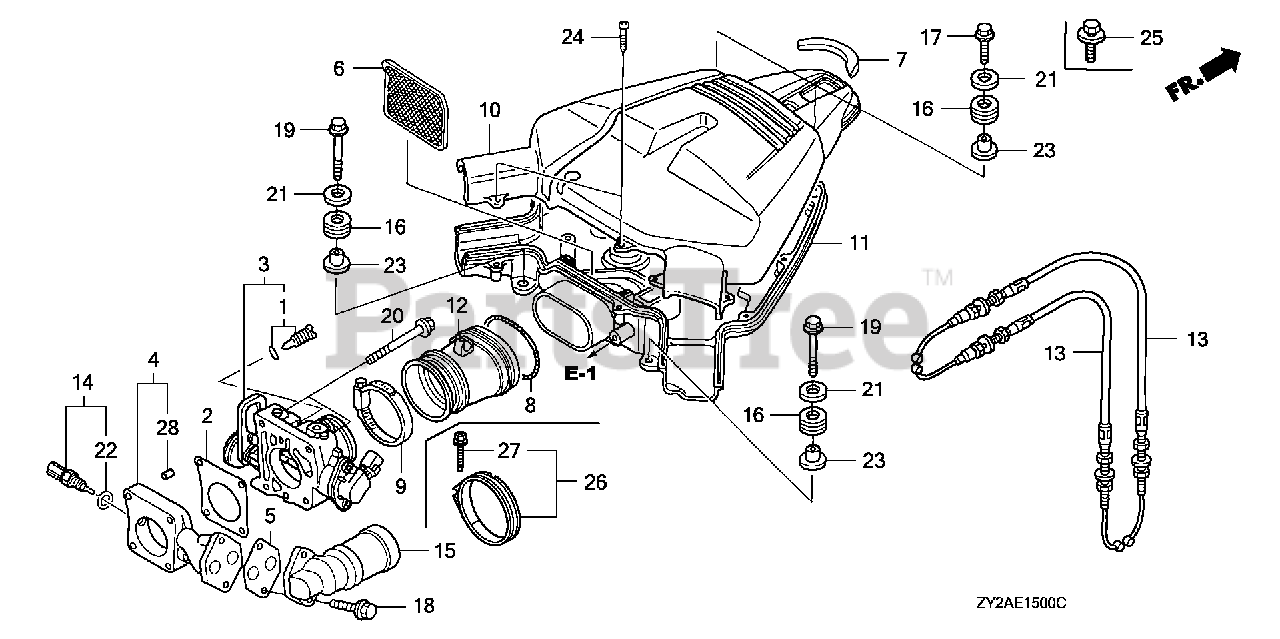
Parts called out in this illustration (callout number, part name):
2	GASKET, THROTTLE BODY
3	BODY ASSY., THROTTLE
4	SPACER, THROTTLE BODY
5	GASKET, EAC VALVE
6	TRAP, FLAME
7	RUBBER, SEAL MUFFLER
8	SPRING, AIR FLOW TUBE
9	BAND, AIR FLOW
10	CASE A, MUFFLER
11	CASE B, MUFFLER
12	GROMMET, MUFFLER
13	CABLE, THROTTLE
14	SENSOR ASSY., AIR TEMPERATURE
15	VALVE ASSY., EAC
16	GROMMET, CASE (LOWER)
18	BOLT, FLANGE (6X22)
19	BOLT, FLANGE (6X60)
20	BOLT, FLANGE (8X65)
21	WASHER, PLAIN (6MM)
23	COLLAR, MODULE IGNITION CONTROL CASE (CDI)
24	SCREW, TAPPING (5X20)
25	BOLT-WASHER (6X25)
26	BAND, AIR FLOW
27	BOLT-WASHER (5X30)
28	PIN, DOWEL (6X10)
